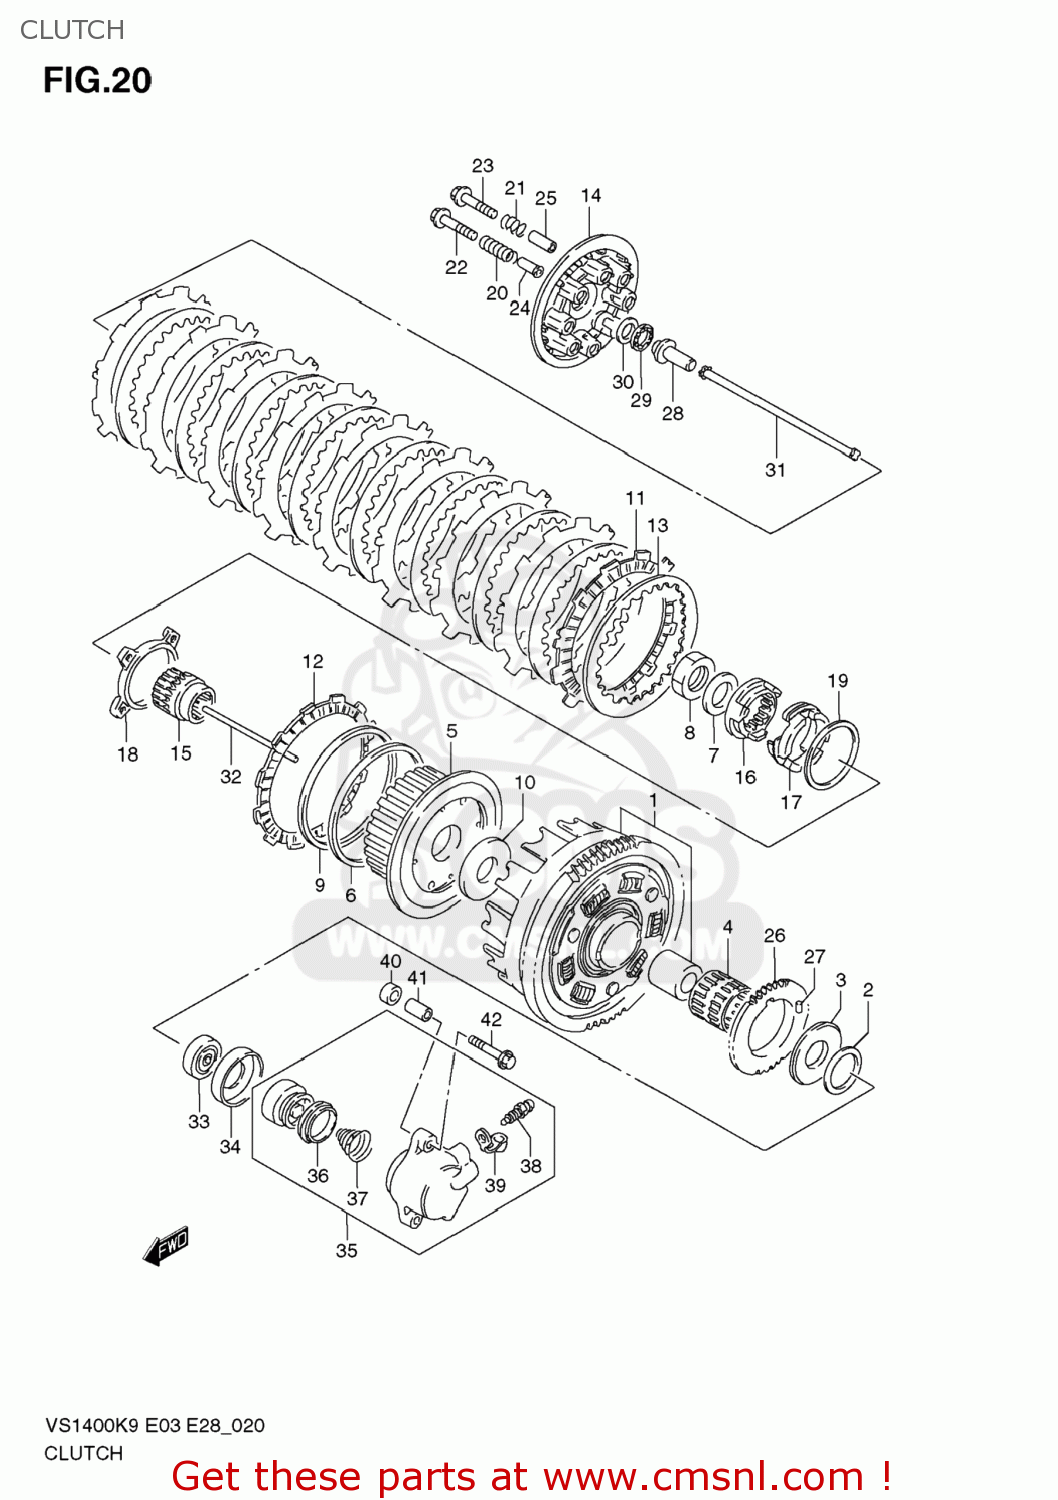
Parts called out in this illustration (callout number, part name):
1	GEAR ASSY,PRI DRIVEN
2	WASHER(25X38X2.5)
3	WASHER(25X54X2.5)
4	BEARING(35X40X35.8)
5	HUB,CLUTCH SLEEVE
6	SEAT,WAVE WASHER(T:1.4)
7	WASHER
8	NUT
9	WASHER
10	WASHER(25X60X2.5)
11	PLATE,CLUTCH DRIVE (NAS)
12	PLATE,CLUTCH DRIVE(T:3.5) (NAS)
13	PLATE,CLUTCH DRIVEN (NAS)
14	DISC,CLUTCH PRESSURE
15	SPACER,CLUTCH SLEEVE HUB
16	CAM,CLUTCH NO.1
17	CAM,CLUTCH NO.2
18	SLIDER,CLUTCH SPRING
19	WASHER(54X62X1)
20	SPRING
21	SPRING
22	BOLT(6X40)
23	BOLT(6X35)
24	SPACER(6.4X10X22)
25	SPACER(6.5X9X24.1)
26	GEAR,OIL PUMP DRIVE
27	PIN(6X6)
28	PIECE,CLUTCH PUSH
29	BEARING(15X28X2)
30	WASHER(15.5X28X1)
31	ROD,CLUTCH PUSH,R
32	ROD,CLUTCH PUSH,L
33	SEAL,OIL(6X34X10.5)
34	RETAINER,CL PUSH ROD OIL SEAL
35	CYLINDER,CLUTCH RELEASE
36	CUP
37	SPRING,CLUTCH CYLINDER
38	BLEEDER
39	CAP,BLEEDER
40	SPACER(9X16X11)
41	PIN(6.4X9X23)
42	BOLT
